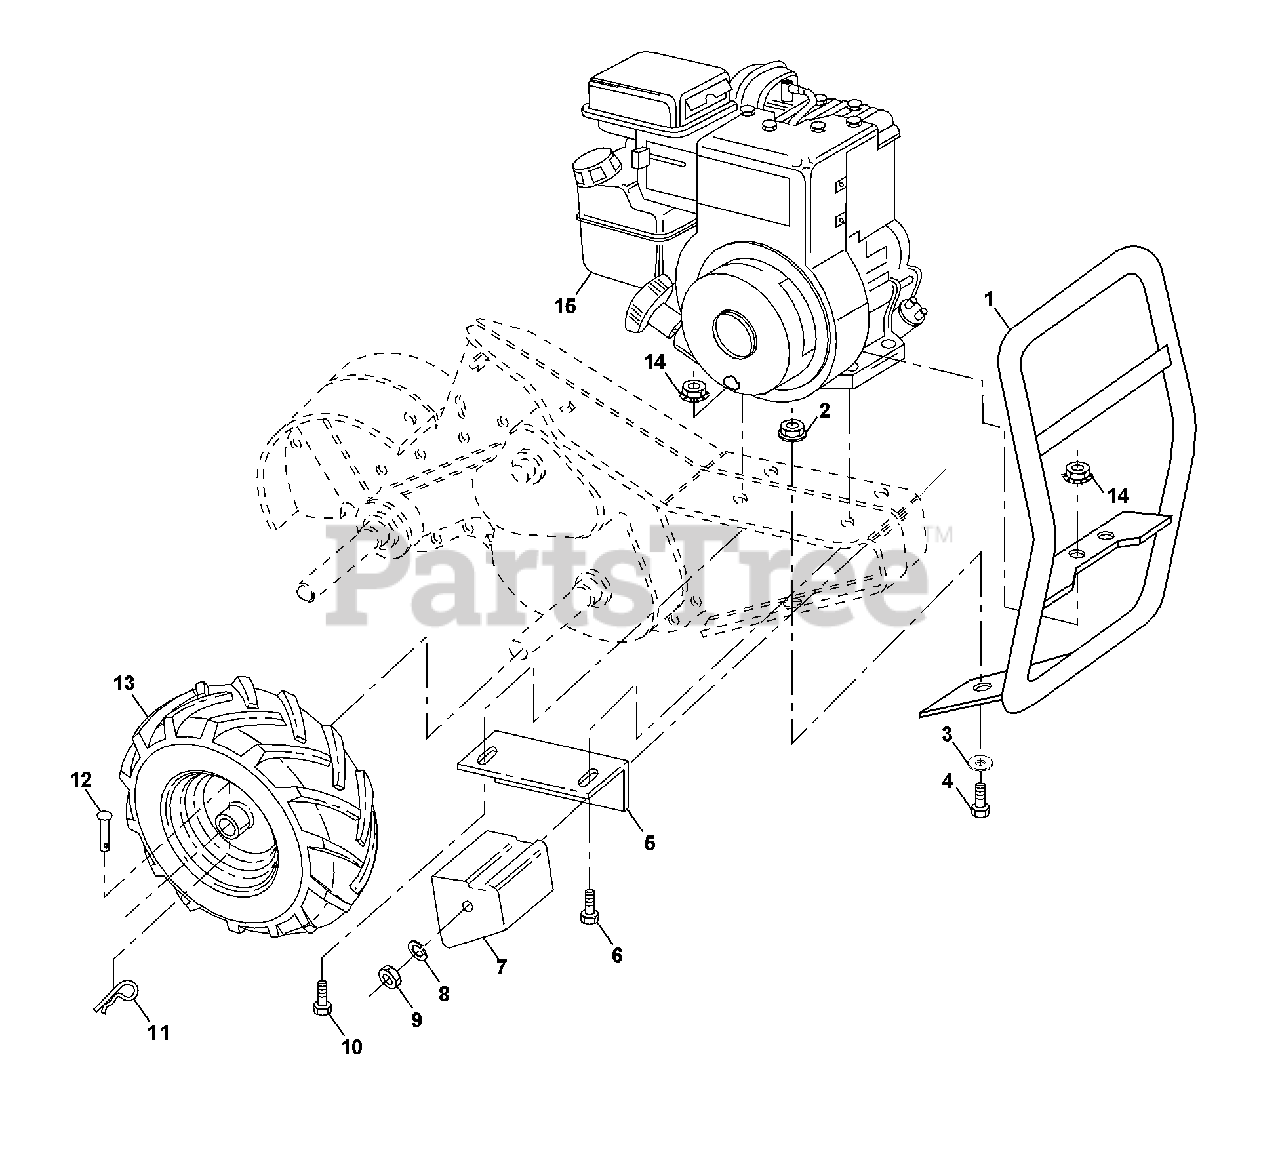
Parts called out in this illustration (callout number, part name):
1	Bumper
2	Nut, Lock hex Flange
3	Washer 11/32 x 11/16 x 16 Ga.
4	Bolt, Hex Hd 5/16-18 x 3/4
5	Bracket, Reinforcement
6	Bolt, Hex 5/16-18 x 2
7	Counter Weight, R.H.
8	Washer, Lock 3/8
9	Nut, Hex 3/8-16
10	Bolt, Hex 5/16-18 x 1-1/2
11	Clip, Hairpin
12	Rivet, Drilled
13	Rim
13	Tire Valve
14	Nut, Keps 5/16-18
